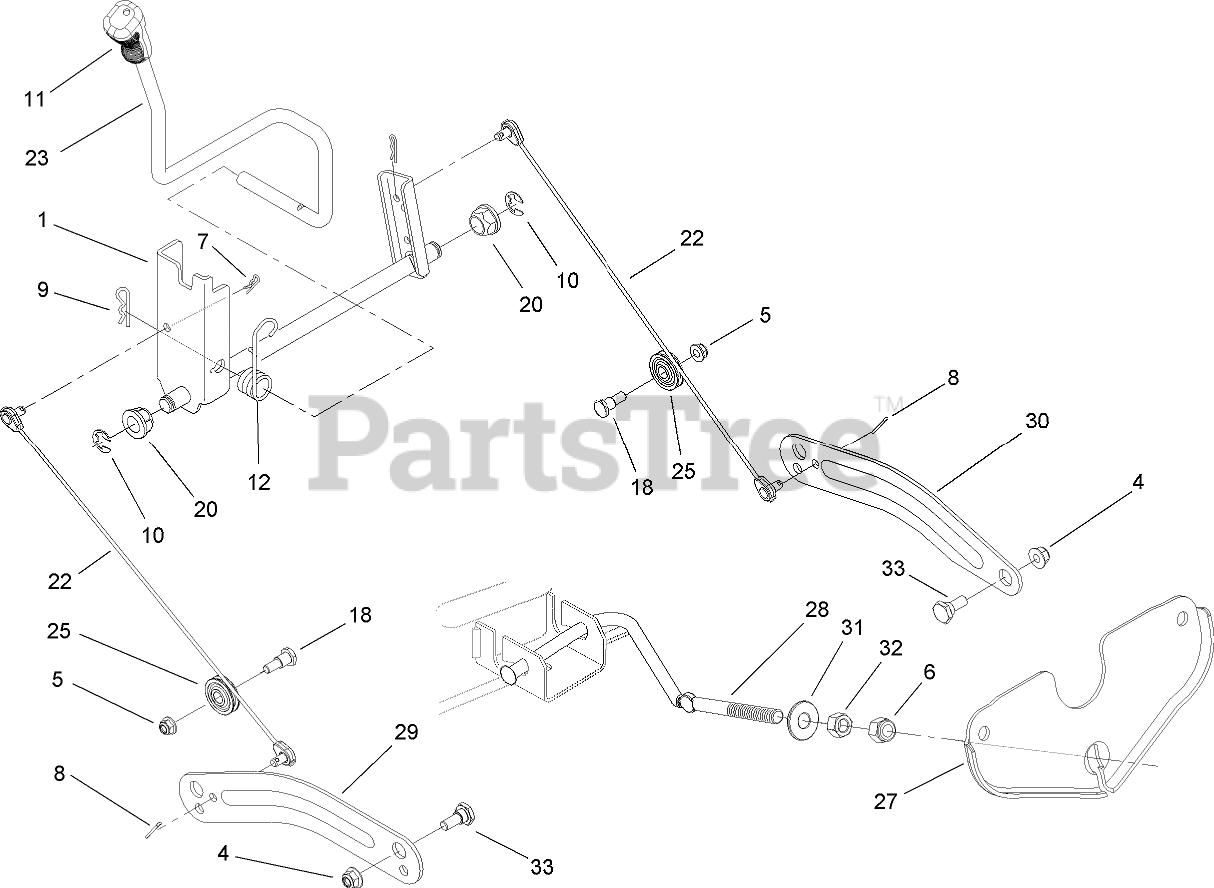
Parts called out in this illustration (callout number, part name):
1	LIFT SHAFT ASM
4	NUT-LOCK, FLANGE
5	NUT-LOCK, FLANGE
6	NUT-LOCK, HEX (NYLON)
7	PIN-COTTER
8	PIN-COTTER
9	PIN-HAIR
10	RING-E
11	GRIP-HANDLE
12	SPRING-TORSION
18	BOLT-SHOULDER
20	BEARING-FLANGE
22	CABLE-LIFT
23	HANDLE-LIFT
25	PULLEY-ROLLER
27	BRACKET-HANGER, DECK
28	ROD-DECK, FRONT ADJUSTMENT
29	ARM-LIFT, DECK (RH)
30	ARM-LIFT, DECK (LH)
31	CUP-PIVOT, LIFT
32	NUT-HEX
33	BOLT-SHOULDER
